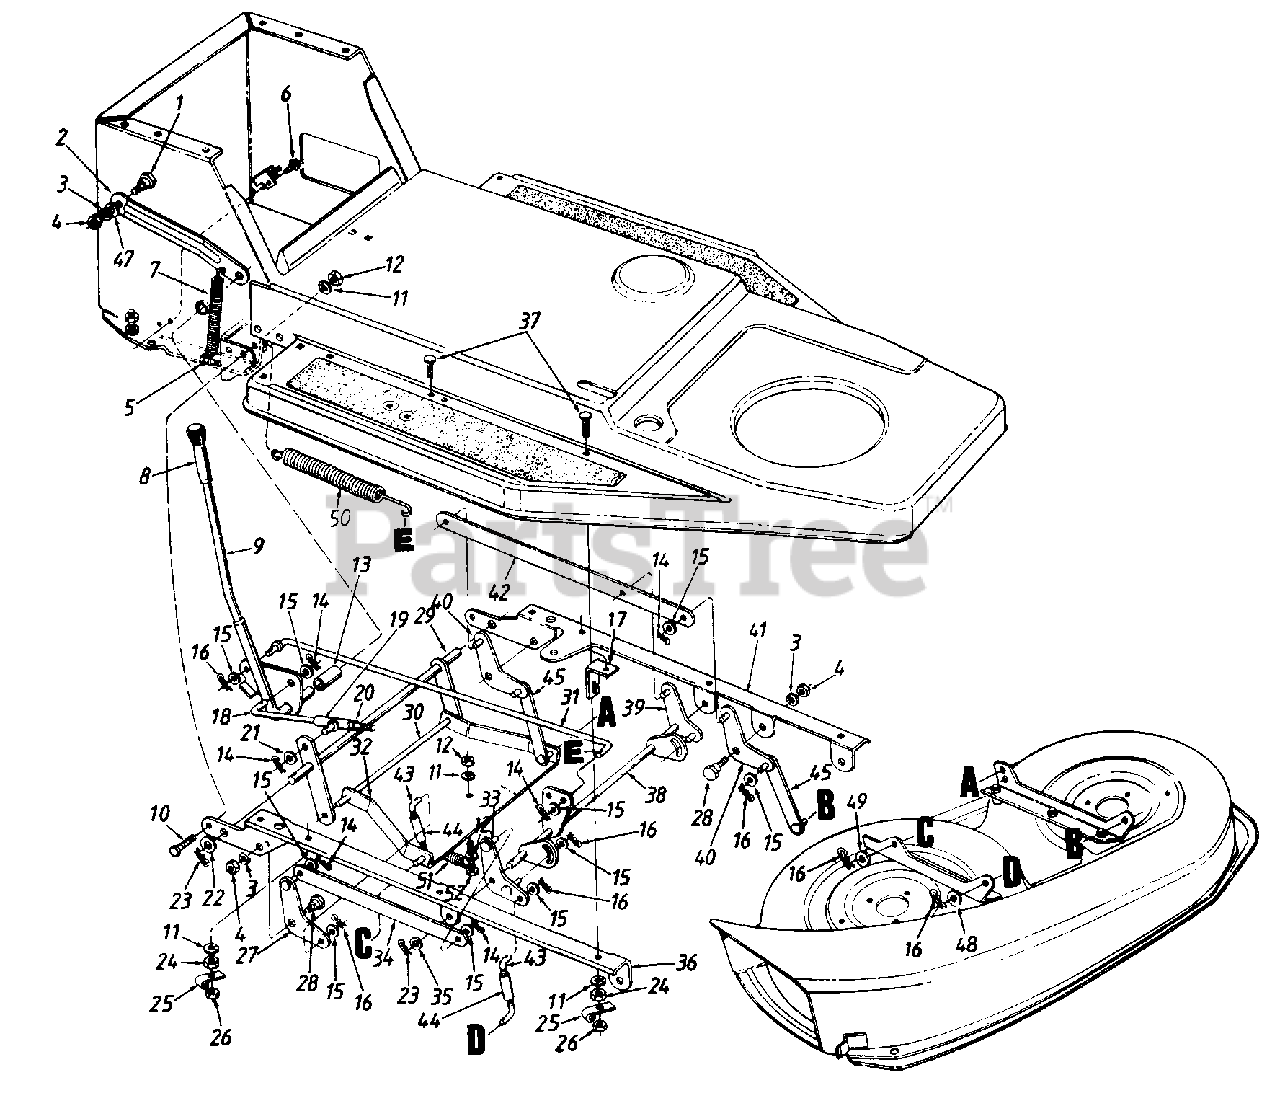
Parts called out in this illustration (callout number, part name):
1	Shld. Bolt .5" Dia. x .34" Lg.
4	Hex Nut 3/8-16 Thd.
5	Hex Bolt 1/4-28 x 1.25" Lg.
6	Hex TT-Tap Scr. 1/4-20 x 5." Lg.
7	Ext. Spring
9	Deck Lift Handle Ass'y.
10	Hex Wash. TT-Tap Scr. 5/16-18 x .62" Lg.
11	L-Wash. 5/16" I.D.
12	Hex Nut 5/16-18 Thd.
13	Spacer 5/8" I.D. x .78"
14	Cot-Pin 3/32" Dia. x .75" Lg.
15	Fl-Wash. .406" I.D. x .75" O.D.
16	Internal Cot-Pin 5/16" Dia.
19	Pivot Sleeve Ass'y.
20	Hex L-Nut 3/8-16 Thd.
21	Thrust Washer .382" I.D.
22	Fl-Wash. .635" I.D. x .93" O.D.
23	Cot-Pin 1/8 Dia. x 1.25" Lg.
24	Hex Nut 5/16-24 Thd.
25	Harness Retainer
26	Hex Cent. L-Nut 5/16-24 Thd.
27	Deck Pivot Brkt. Ass'y. - R.H. Rear
28	Shld. Bolt .625" Dia. x .170" Lg.
31	Deck Lift Rod
44	Adj. Lift Link Ass'y.
45	Deck Lift Link Ass'y.
47	Fl-Wash. .531" I.D. x .94"
48	Fl-Wash. .406" I.D. x .75"
49	Fl-Wash. 3/8" I.D.
50	Ext. Spring .87" Dia.
51	Ext. Spring 11" Lg.
52	Hex Bolt 5/16-18 x 7/8" Lg.
